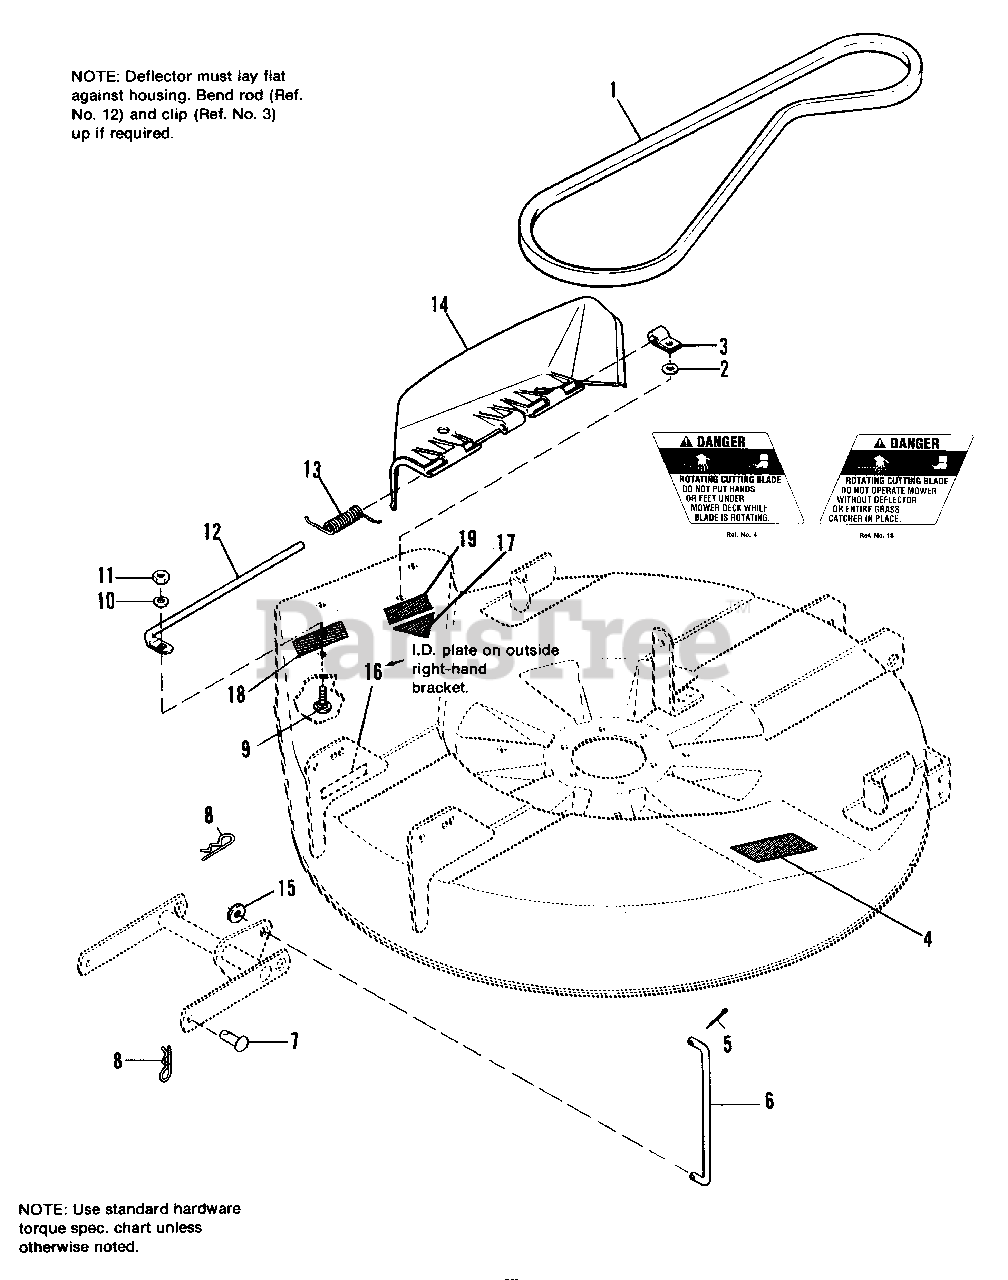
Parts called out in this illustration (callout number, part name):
2	WASHER, Plain, 9/32
4	DECAL, Danger
5	PIN, Cotter, 3/32 x 1
8	CUP, Hairpin
9	BOLT, Carriage, 1/4-20 x 3/4
10	LOCKWASHER, 1/4
11	NUT, Hex, 1/4-20
12	ROD, Deflector, Front
15	WASHER, Plain, 3/8
16	PLATE, I.D.
17	DECAL, OPEI
18	DECAL, Danger, Mower
19	DECAL, Cutting Width, 30"
